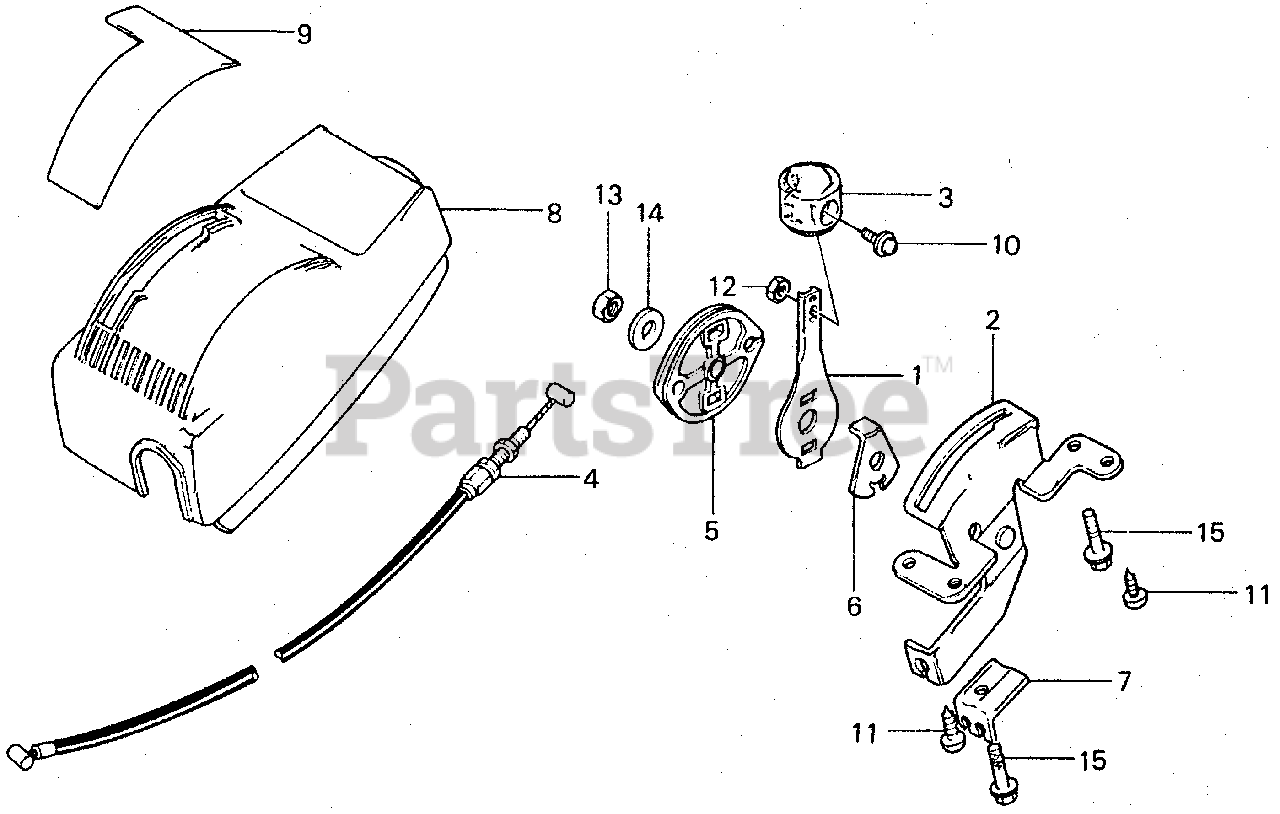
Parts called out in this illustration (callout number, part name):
1	LEVER, THROTTLE
2	BASE, THROTTLE LEVER
3	KNOB, THROTTLE LEVER
4	CABLE, THROTTLE (NOT AVAILABLE)
5	REEL, CONTROL CABLE
6	STOPPER, REEL
7	STAY, CABLE
8	COVER, CONTROL
9	MARK, CONTROL (ENGLISH) (NOT AVAILABLE)
10	SCREW-WASHER (4X8)
11	SCREW, TAPPING (5X12)
12	NUT, HEX. (4MM)
13	NUT, HEX. (6MM)
14	WASHER, PLAIN (6MM)
15	BOLT, FLANGE (6X32)
